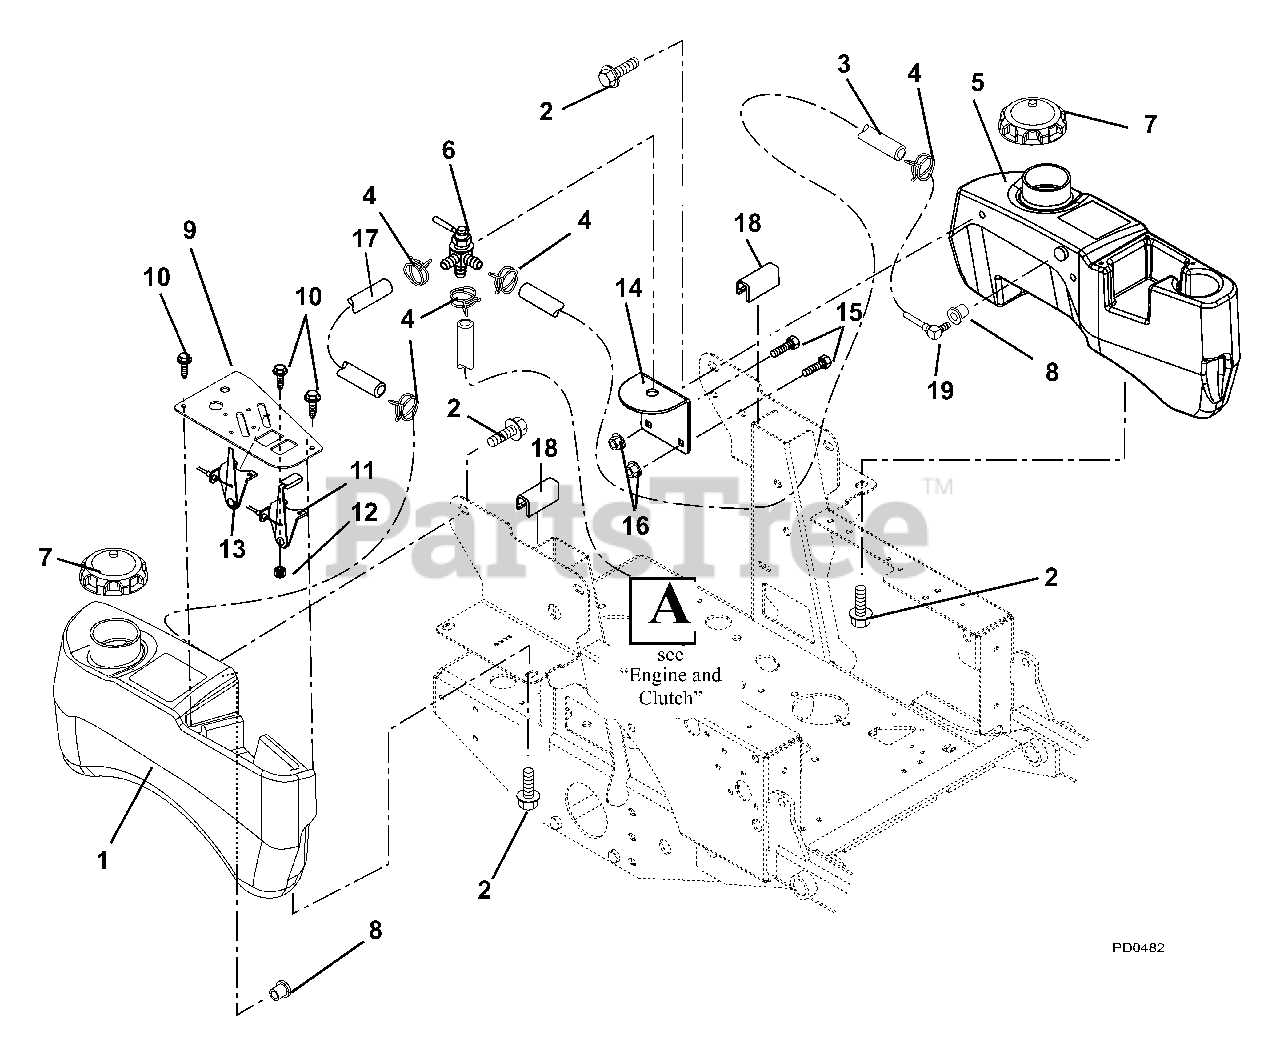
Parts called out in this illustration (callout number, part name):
1	Tank, Gas- Right Hand
2	Bolt, SEMS .31-18 x .62
3	Hose, Gas Line 6.25"-.25" I.D.
4	Hose, Clamp
5	Tank, Left Hand Fuel (Eye-Q)
6	Valve, Fuel
7	Cap, Fuel
8	Grommet
9	Panel, Control
10	Screw, Machine 10-24 x .50 Hex Washer Head
11	Cable, Throttle Choke
12	Nut, Locking Nylon 10-24 With Insert
13	Cable, Choke
13	Cable, Choke/Throttle
14	Bracket, Fuel Valve Mounting
15	Bolt, Round Head Square Neck .31-18 x .75 Grade 5
16	Nut, Nyloc Flange 5/16-18
17	Hose, Gas Line 29"-.25" I.D.
18	Cowl Strip 1.75" Long
19	Fitting, Tank Elbow .31 Hose
